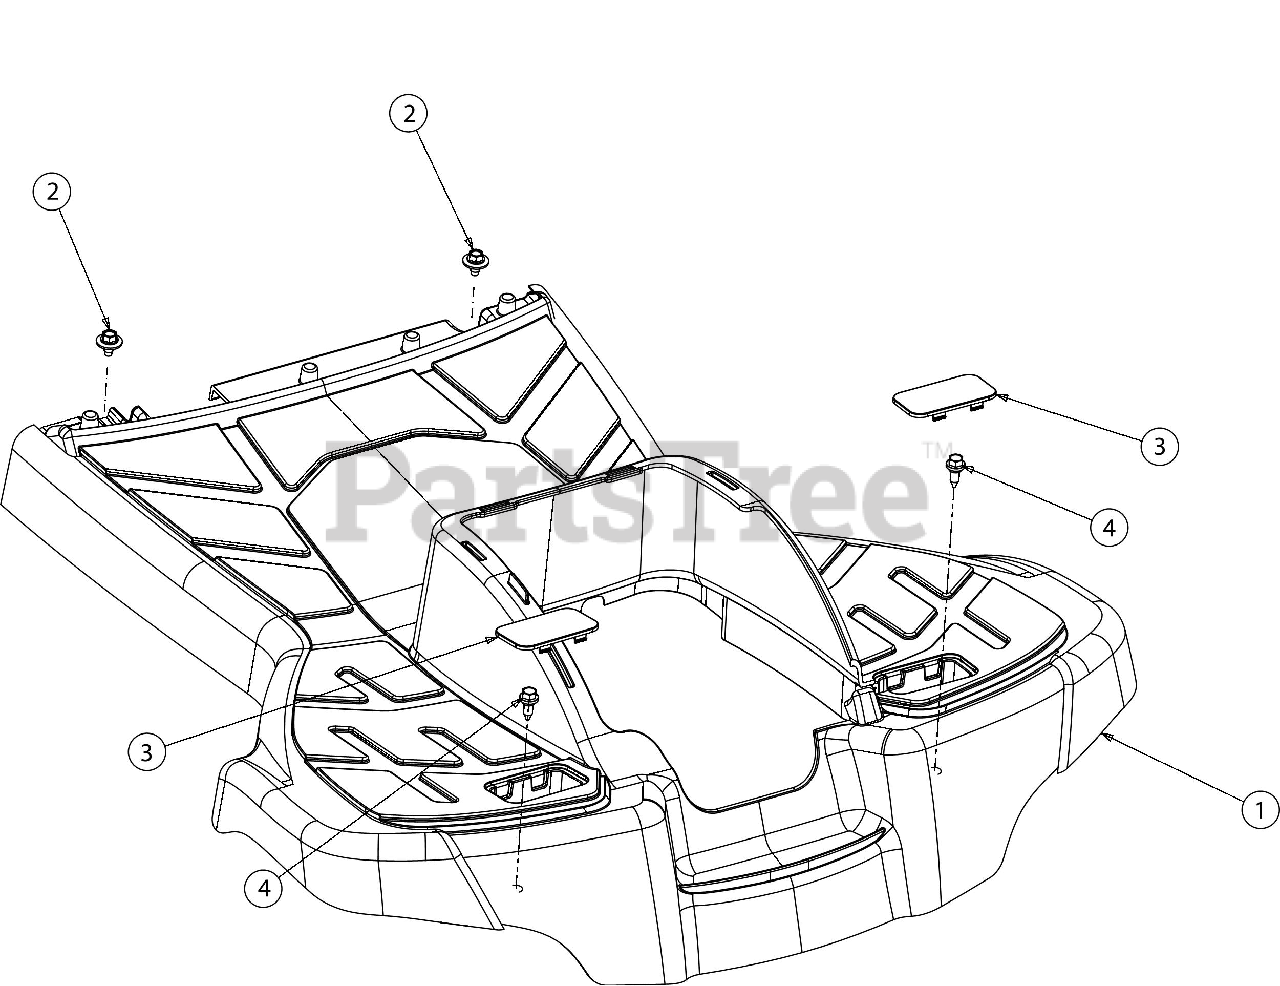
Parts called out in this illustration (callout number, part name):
1	RUNNING BOARD
2	SCREW 1/4-20 x .50
3	RUNNING BOARD PLUG
4	SHOULDER SCREW
